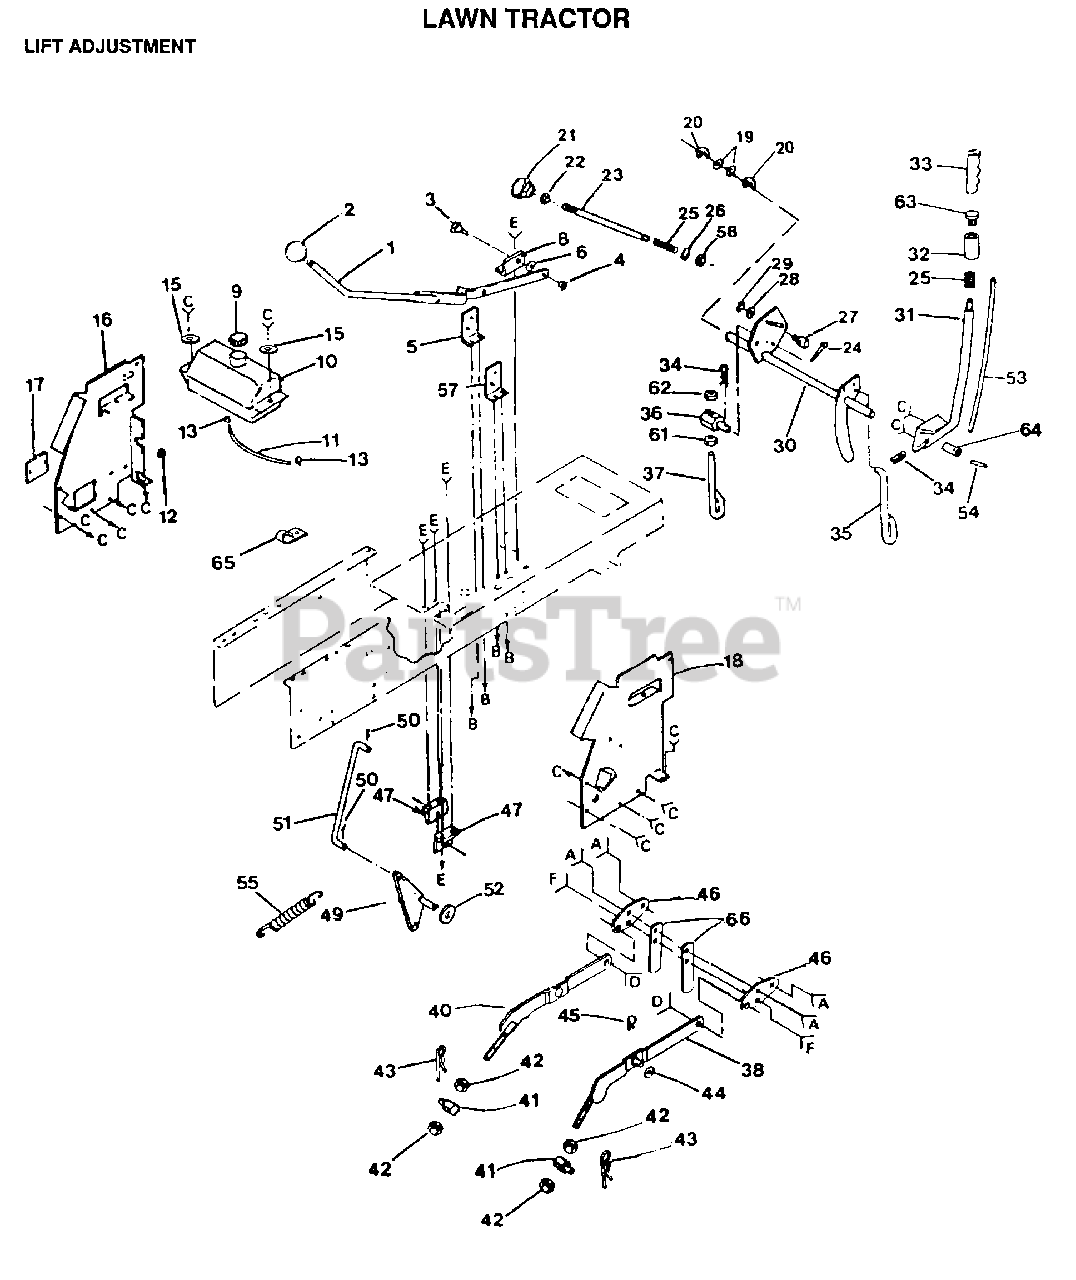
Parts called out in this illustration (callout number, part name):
3	"BOLT, SHOULDER LT"
5	"BRACKET,SWITCH LT"
8	"SUP,LVR,CLUTCH LT"
10	TANK.FUEL.LT.
11	FUEL LINE T
12	SNAP BUSHING T
13	HOSE CLAMP
15	WASHER GT
17	COVER ACCESS
19	WASHER
20	E-RING
22	NUT
25	SPRING T
26	WASHER
27	TRUNION LT
28	WASHER
29	KLIP RING
31	LEVER ASSY LT
33	GRIP
35	LIFT LINK LT
37	PIVOT PIN T
38	RH SUSP ARM ASM
40	LH SUSP ARM ASM
42	NUT
43	SPRING H
45	SPRING.RETAINER
46	"BRACKET, SUSPE T"
47	"BRKT,BELLCRAN T"
49	"T, BELLCRANK"
50	COTTER PIN
51	ROD CLUTCH T
52	WASHER
54	PIN-GROOVE LT
57	BRACKET LT
58	NUT T
61	NUT
64	COUPLE LEVER T
65	INSUL CLIP T
66	UPSTOP
